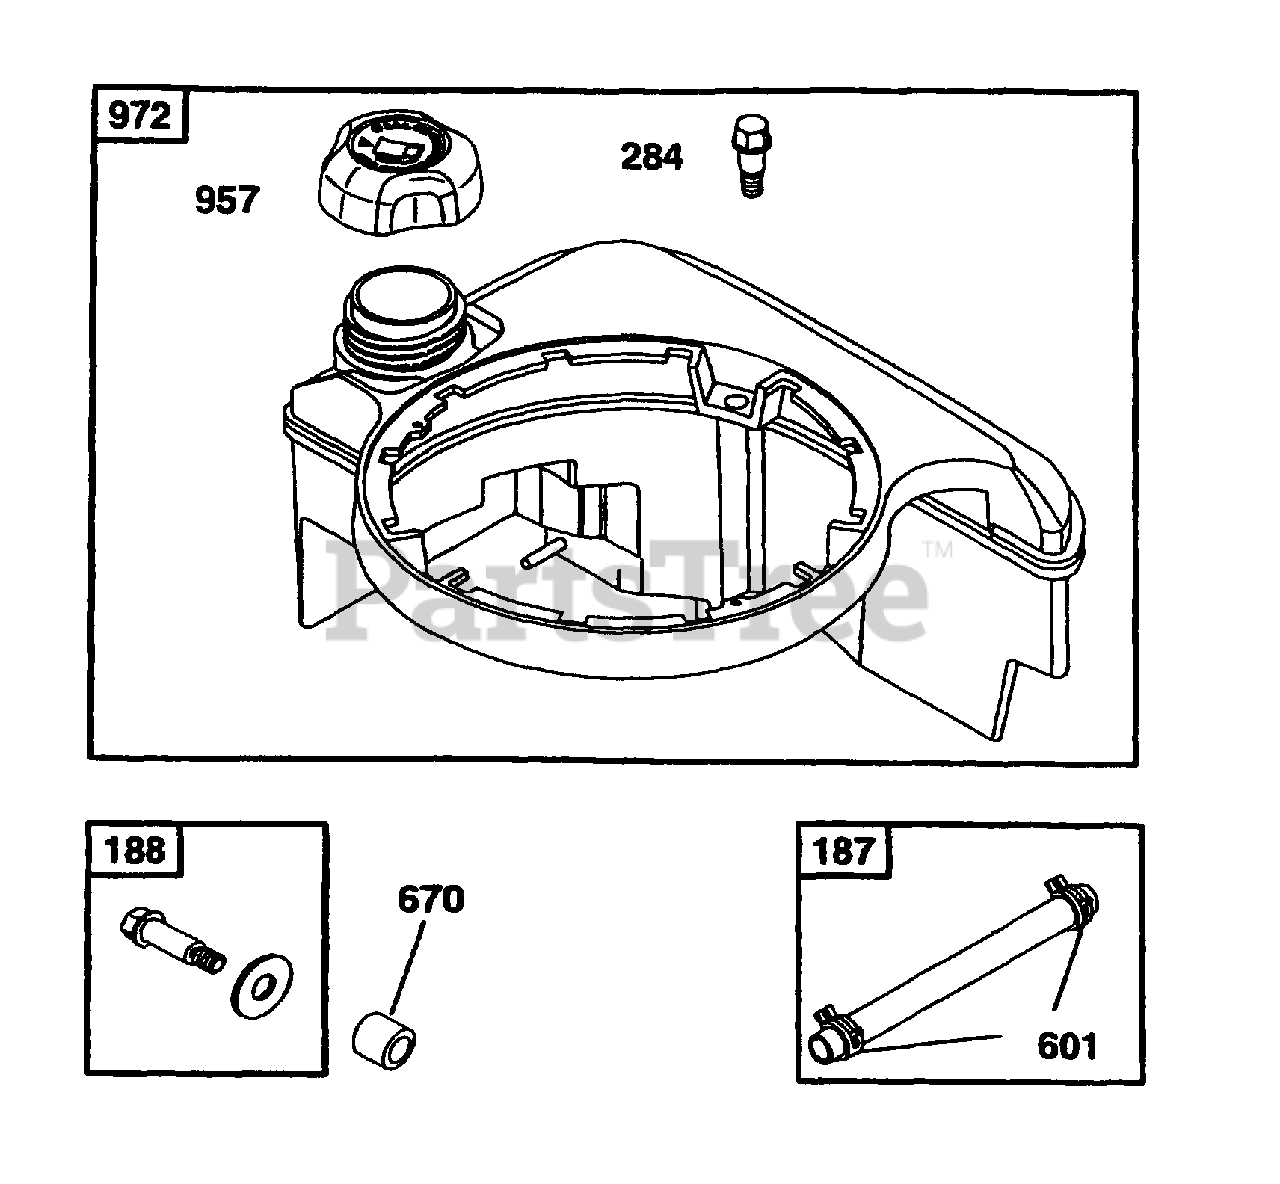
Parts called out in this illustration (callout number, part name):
187	Fuel line
188	Shoulder Screw
284	Shoulder Screw
601	Hose Clamp
670	Fuel Tank Spacer
957	Fuel Tank Cap
972	Fuel Tank
